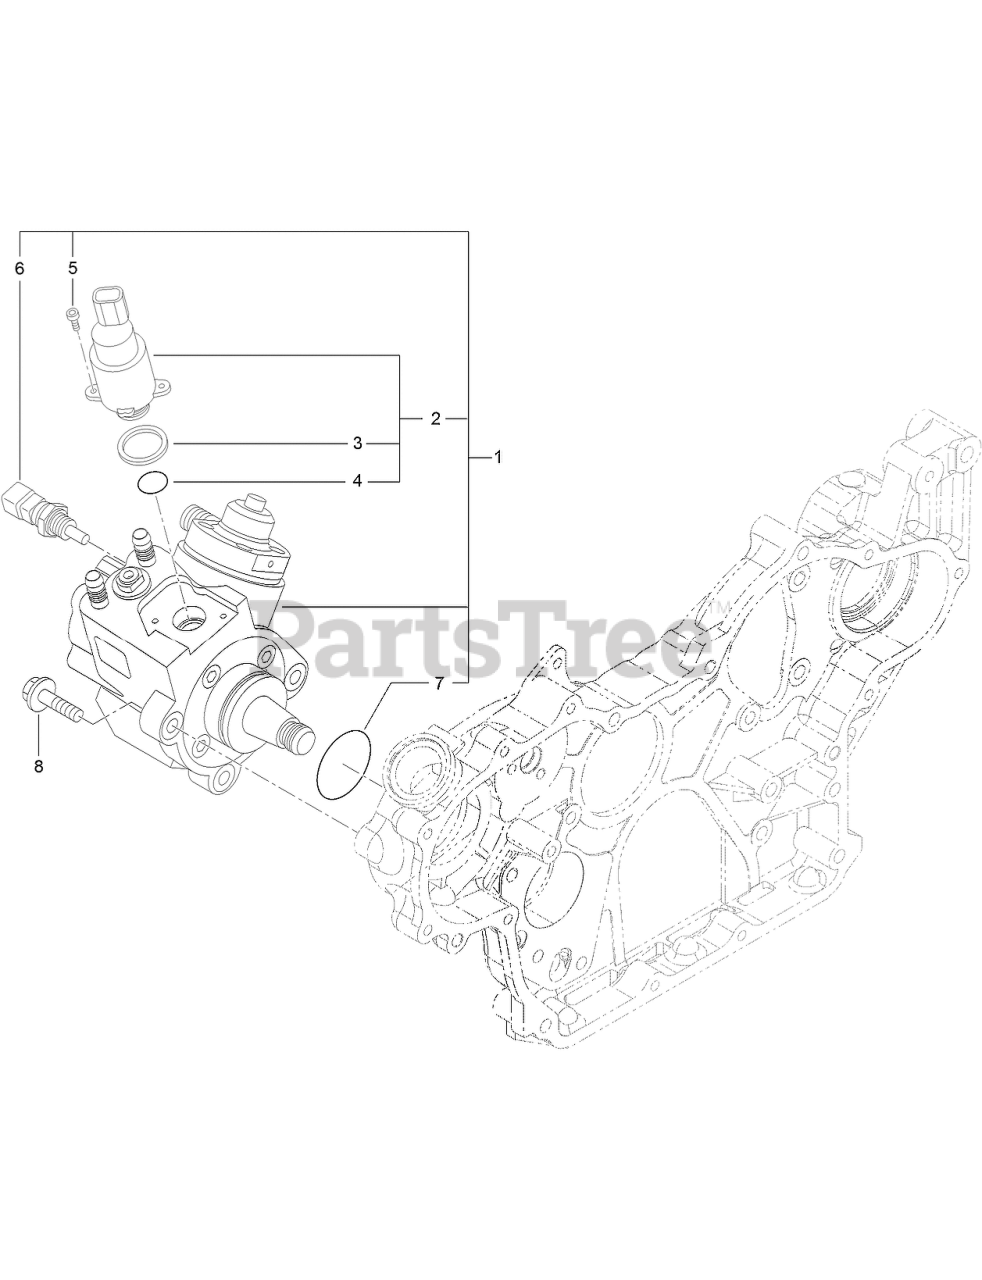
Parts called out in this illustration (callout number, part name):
1	FUEL PUMP ASM
2	VALVE ASM
3	RING-SEALING
6	SENSOR-TEMPERATURE
